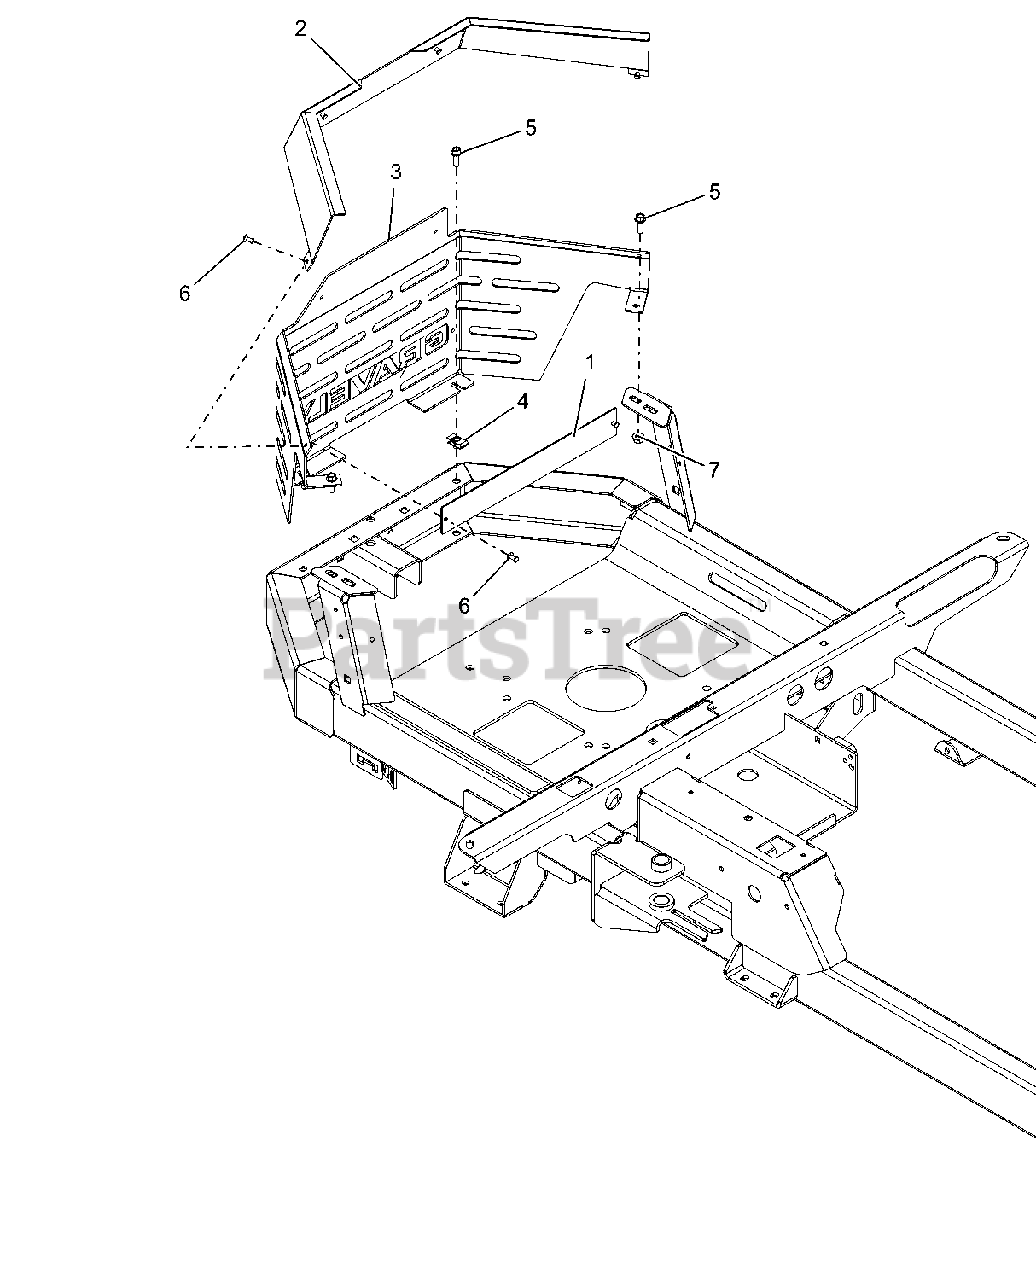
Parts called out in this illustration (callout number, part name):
1	PLATE, SHROUD BACKER
2	BRKT, ENGINE SHROUD TRIM
3	SHROUD, ENGINE GRAVELY
4	NUT, RTNR .25-20 X .56
5	BLT-HEX .25-20X.75 HWH YWZC GR5
6	RVT-POP .187x.375 (#66) BLACK
7	NUT, LK-TOP-FLG .25-20 YWZC
